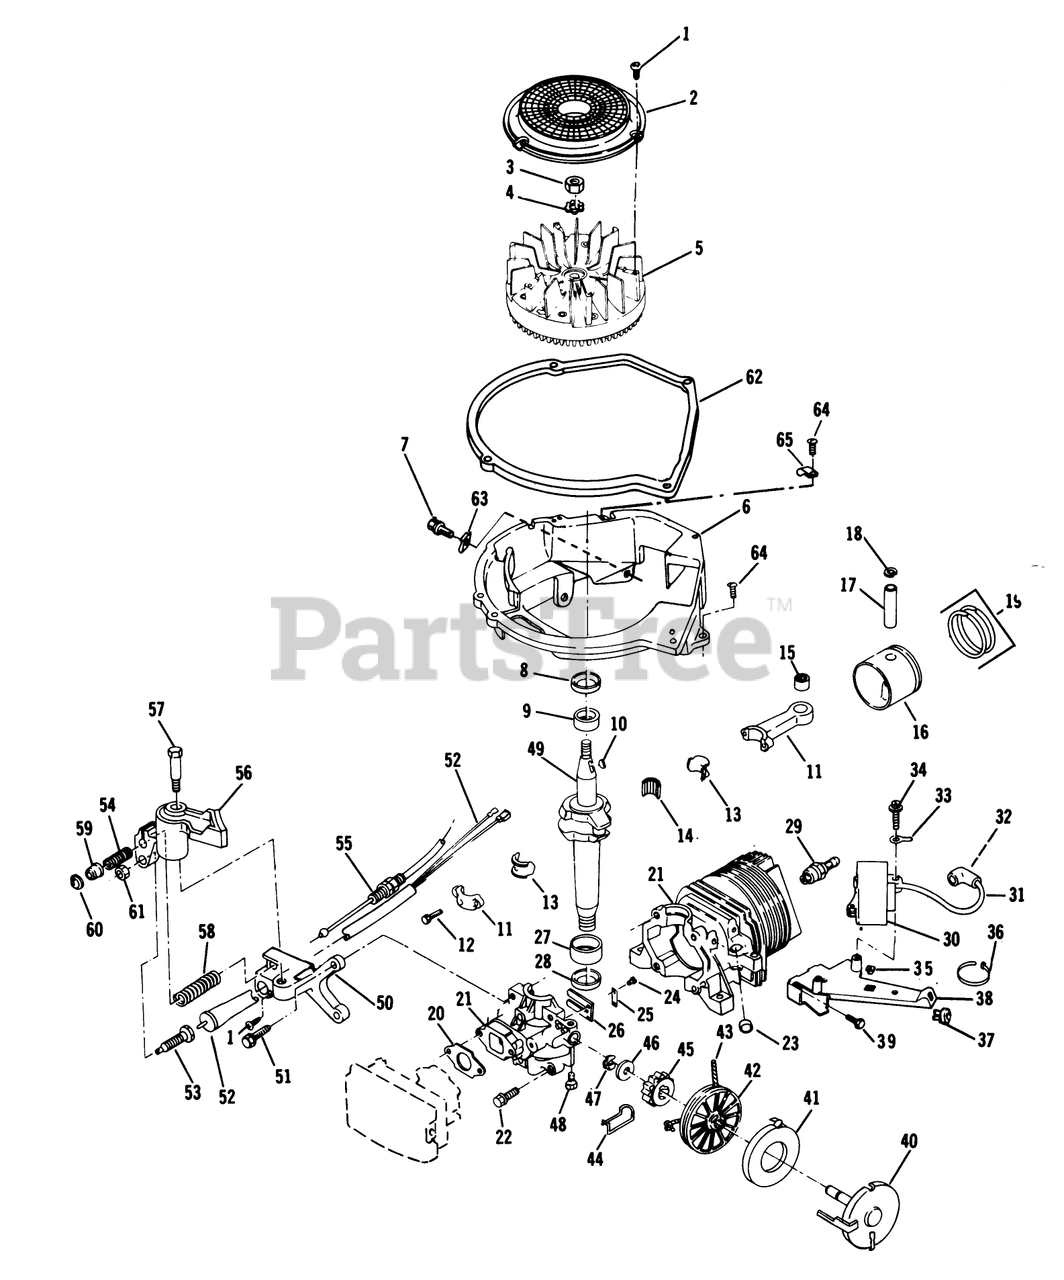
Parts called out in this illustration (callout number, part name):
1	SCREW F
3	NUT
7	SCREW-SEMS
9	BEARING V
10	KEY
12	SCREW-HSH
13	LINER ASM
15	BEARING AY F
18	RING-RETAINING
20	GASKET CARB S
22	SCREW S
23	PLUG-CORE VF
25	PLATE-BACKUP, REED
27	BEARING V
28	SEAL-OIL
31	HT LEAD&COVER XEV
33	TERMINAL S
35	NUT-CLIP
37	NUT-CLIP
40	SPRING CUP&PIN S
41	SPRING&RET.AY S
42	PULLEY STARTER S
43	ROPE-STARTER
46	WASHER S
50	BRACKET-BRAKE F
53	PLUNGER S
54	SPRING
55	CONTROL CABLE WES
58	SPRING-BRAKE
59	ACTUATOR-LEVER, BRAKE
60	RETAINER S
64	SCREW F
